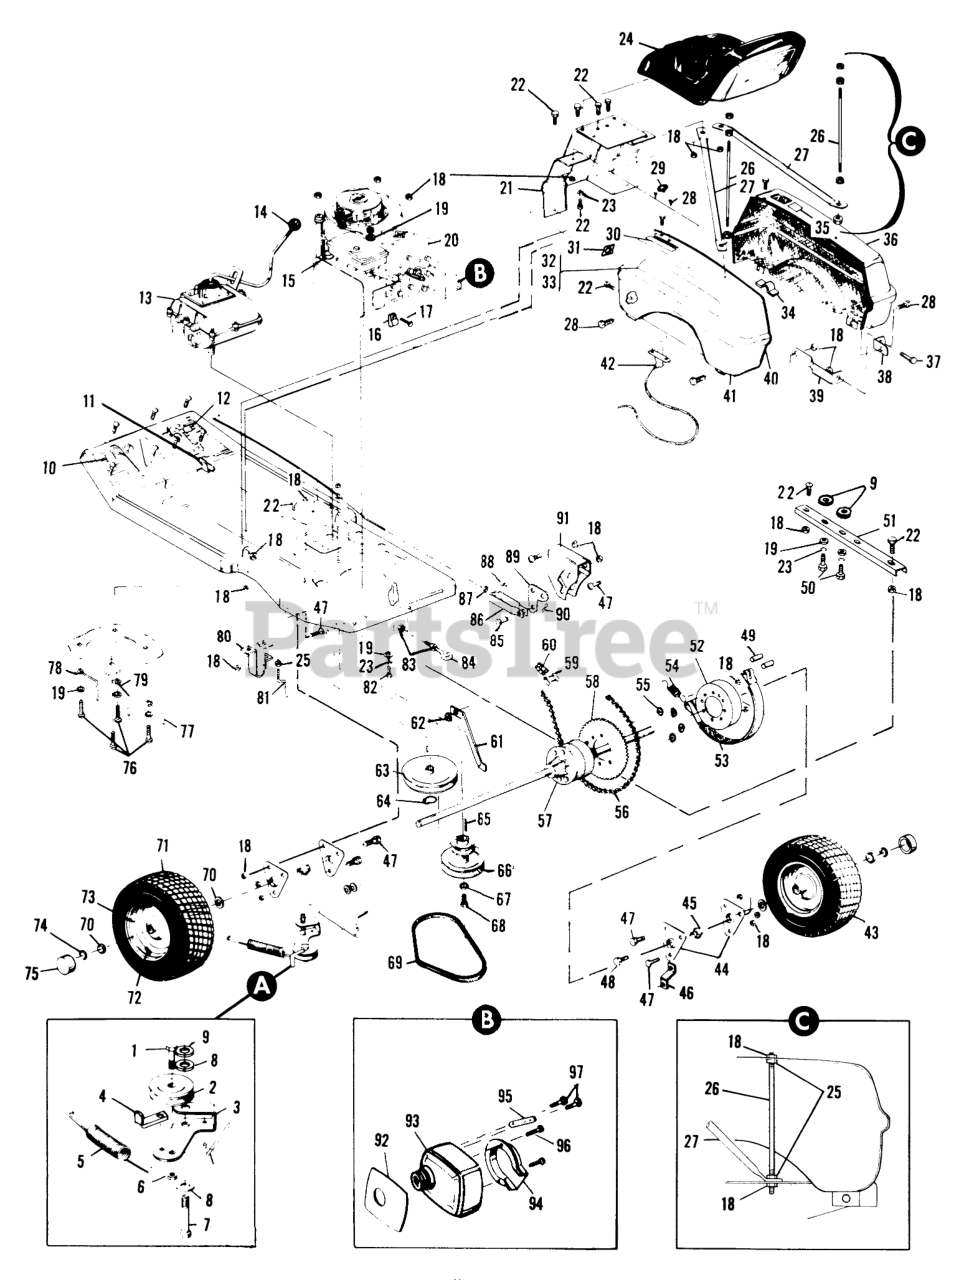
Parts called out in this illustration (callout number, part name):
1	Screw-Cap, Hex. Hd.
2	Idler Pulley
3	Idler Arm
4	Arm, Idler
5	Spring, Brake
6	Nut
7	Shoulder Bolt
8	Washer
9	Washer
10	Decal, Clutch
11	Decal, Parking Brake
12	Decal, Brake
13	Transmission Assembly Complete
15	Gas Gauge
16	Clip, Throttle Cable
17	Screw, Hex Hd, No.10-32 x 5/8 In.
18	Nut-Nylok
19	Washer
20	Engine
21	Support, Seat
22	Bolt Hex 5/16-18
23	Lockwasher
25	Nut 5/16-18 Keps
26	Rod, Fender Reinforcing
27	Strut, Seat Support
28	Screw, Taptite, 1/4-20 x 5/8 In.
29	Knob, Throttle Control
30	Decal, Throttle
31	Decal, lgnition
32	Decal, Body, R.H.
33	Decal, Body, L.H.
34	Press Clip
35	Decal, Shift Pattern
36	Fender, Right
37	Hex Cap Screw
38	Bracket, Chain Adjust
39	Strap, Chain Adjust
40	Edging
41	Fender, Left
42	Control, Throttle
43	Wheel & Tire Assembly
44	Plate, Bearing Retainer
45	Bearing, Rear Axle
46	Retainer, Brake Band
47	Carriage Bolt, 5/16-18 x 5/8 In.
48	Bolt-3/8-16 x 3/4
49	SPIROL PIN 3/8X1 3/4
50	Screw-Cap Hex. Hd.
51	Channel Stiffner
52	Drum, Brake
53	Brake Band Assembly
54	Brake Return Spring
55	Spacer
56	Chain Assy (With Link)
57	Differential, Peerless Model 172A (See Warranty, Page 2)
58	Sprocket, 40 Tooth (Differential Part)
59	Connector Link (Only)
60	Link, Offset
61	Belt Guide
62	Nut-Nylok
63	Bracket-Link
64	Snap Ring
65	Key, Square, 1/4 X 1/4 X 1 1/2 In.
66	Pulley, Engine
67	Lockwasher, Split, 3/8 In.
68	Screw, Hex Hd, 3/8-24 x 1 In.
69	"V" Belt, 4241
70	Flatwasher
71	Tire, 4.10-3.50 x 6
72	Valve Stem
72	Tag, Warranty (Not Illustr.)
73	Wheel
74	"E" Ring
75	Hub Cap
76	Bolt 5/16-18 x 1/2
77	Belt Guide
78	Belt Guide
79	Belt Guide
80	Bracket, Clutch Spring Assy
81	Belt Guide
82	Screw, Hex Hd, 5/16-18 x 3/4 In.
83	Nut
84	Eyebolt, Trailer Hitch
86	Clevis
87	Nut, Hex, 1/4-20 Thd
88	Nut, Square, 1/4-20 Thd
89	Brake Lever
90	Cotter Pin, 3/32 x 3/4 In.
91	Brake Cam Plate Assy
92	Heat Shield (Engine Part)
93	Muffler, Lo-Tone
94	Deflector, Muffler
95	Lock Strip, Muffler Mounting
96	Screw
97	Screw
